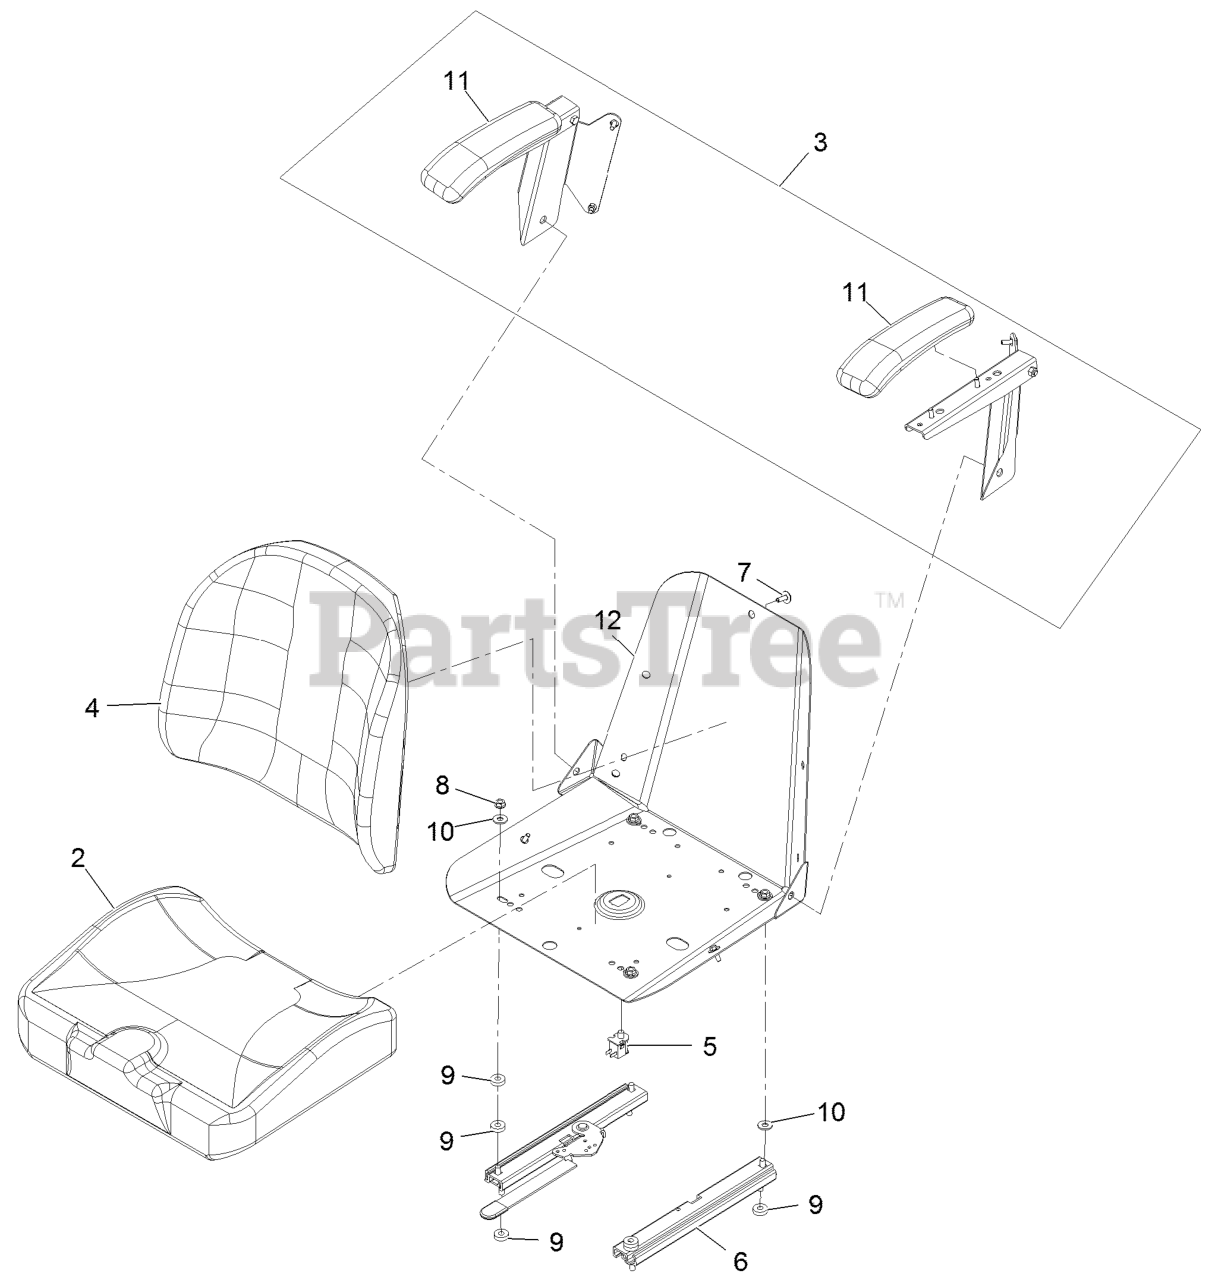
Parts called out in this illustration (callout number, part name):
2	CUSHION-SEAT BOTTOM
3	ARMREST KIT
4	CUSHION,SEAT BACK
5	SWITCH-BAIL
6	TRACK-SEAT
7	BOLT-SEAT
10	WASHER-FLAT
11	CUSHION-REST, ARM
12	FRAME-SEAT
